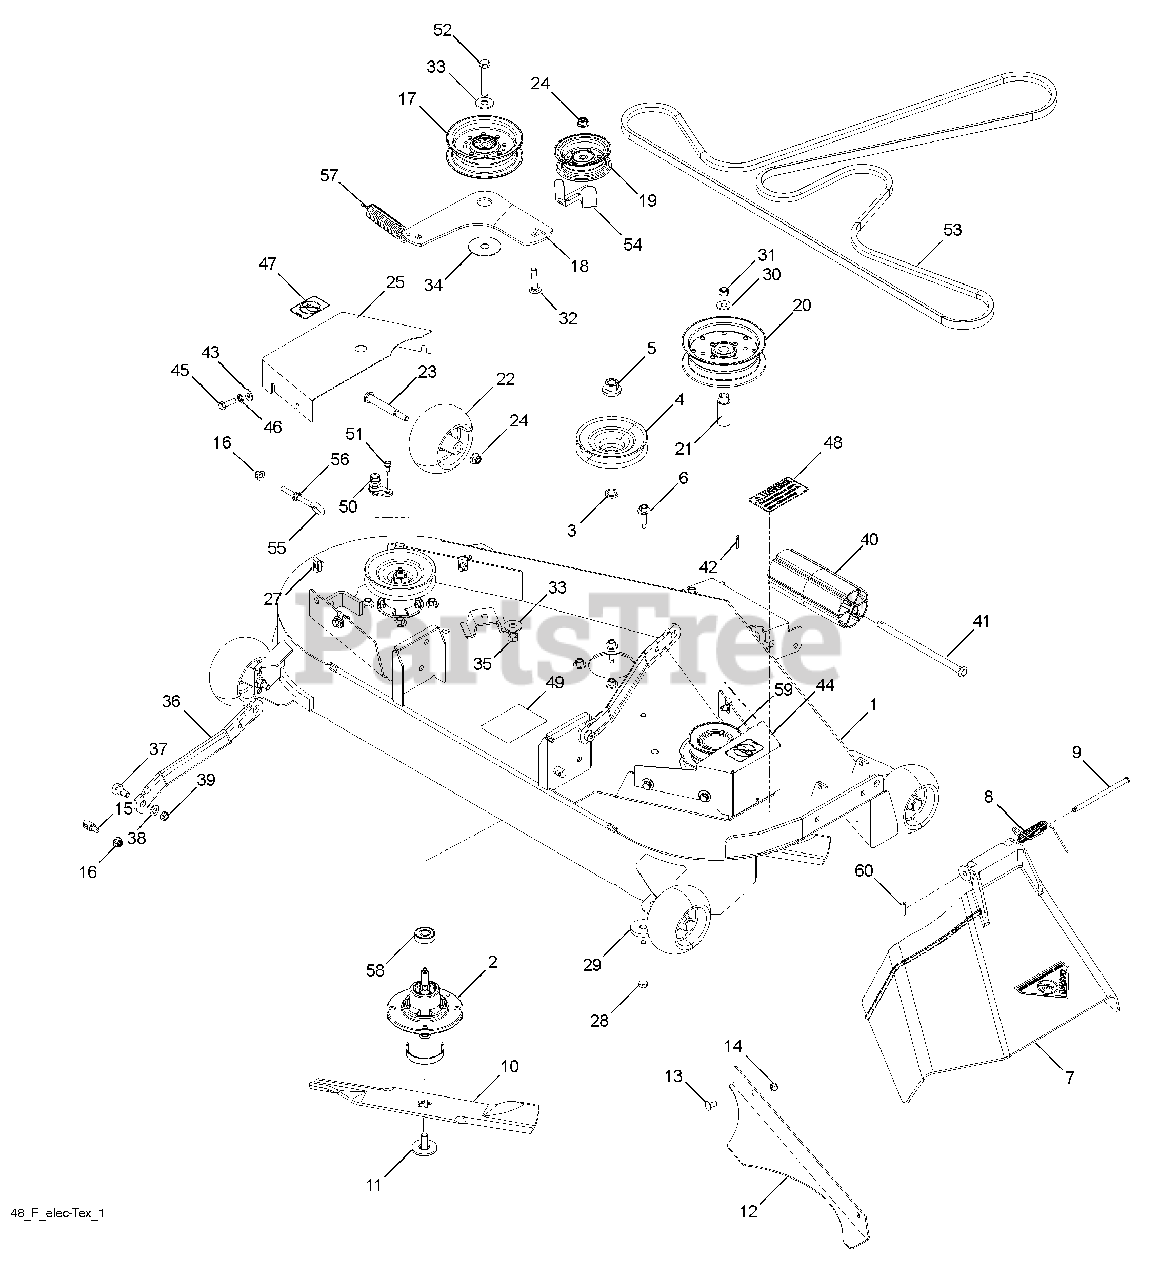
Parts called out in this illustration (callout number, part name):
1	Deck w/ Decals 48"
2	Housing Assembly
3	Washer-Spacer
4	Pulley, Mandrel
5	Nut, 9/16 Top Center Lock
6	Screw, Washer Head
7	Discharge Chute, 48"
8	Spring - Torsion
9	Pin, Clevis 5/16 x 5.19
10	Blade, 16-1/4"
11	Bolt, 7/16, Assy Blade
12	Confinement Plate
13	Rhsnb 5/16-18 x 5/8 Gr 5
14	Nut 5/16-18 Hex Nyloc
15	Stud, Fasten w/ Anti- Rotate
16	Nut 5/16-18 Hex Flange Nyloc
17	Pulley, Idler Spec. Hub
18	Arm, Idler, Blk
19	Pulley, Idler
20	Pulley, Idler
21	Idler Bushing
22	Wheel, Gauge
23	Bolt, Shoulder
24	Nut 3/8-16 Hex Flg Nyloc
25	Shield, Belt LH
27	Retainer 5/16c U Type
28	Hcs 3/8-16 x 3-1/2 Gr 5
29	Heavy Washer
30	Washer, 3/8 Flat Std
31	Nut 3/8-16 Hex Nyloc
32	Rhsnb 3/8-16 x 1-3/4 Gr 5
33	Washer, 7/16 Flat
34	Washer, Flat Hardened
35	Nut, 7/16-14 Hex Nyloc
36	Arm, Susp., Rear
37	Sb 3/8-16 x 3/8 Skt Hd
38	Washer, 3/8 Sae Flt
39	Nut, 3/8-16 Hex Jam Nyloc
40	Roller, Nose, 48"
41	Rod, Roller, Nose, Narrow
42	Clip Reatainer 0.375
43	Washer, 5/16 Std Flt
44	Shield, Belt Rh
45	Hcs 5/16-18 x 1 Gr 5
46	Wash 5/16 Slw
47	Decal, No Step
48	Decal, Warning
49	Decal, Deck Sch
50	Washout Port
51	Bolt, 1/4-20 x 1/2
52	Hcs 7/16-14 x 2-1/2 Gr 5
53	Belt, Deck
54	Guard, Belt
55	Eyebolt 5/16 x 3-1/2
56	Nut 5/16-18 Hex Whizlk
58	Ball Bearing
59	Pulley
60	Clip Retainer Dia. 290
